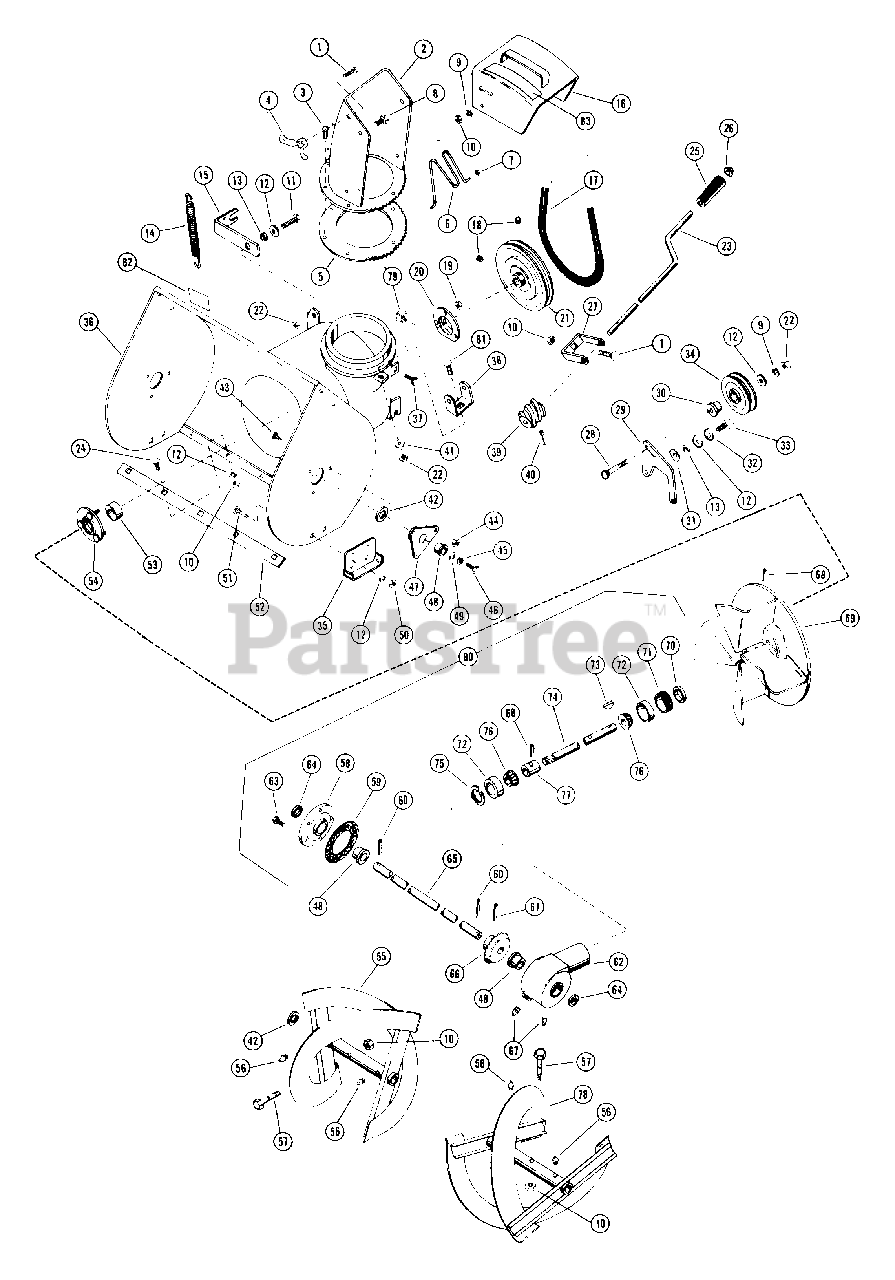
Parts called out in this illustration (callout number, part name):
1	BLT-RDHDSQSHNK .31-18X.50 YZ
2	DISCHARGE CHUTE
3	SCR-TAP 8-32X.38 SL HWH PL 23
4	WING NUT, .312-18
5	LOWER COLLAR GEAR
6	SAFETY WIRE
7	FASTENER
8	BLT-HEX .31-18X.50 PL GR2
9	WSHR-LK .312X.097 PL HVY
10	NUT-LK .312-18 GR A PL
11	BLT-HEX .31-18X.75 PL GR2
12	WSHR-FL-STL .38X.875X.083 PL
13	SPACER BUSHING .5 X .32 X .21
14	SG-TENS .125X.437X5.5 WLD 20
15	CLUTCH LEVER
16	DEFLECTOR SERVICE ASSEMBLY
17	V-BELT, 4L-WRAPPED
18	SCR-SET .32-18X.38 SKHCUPNL OH
19	NUT-LK-CTR .250-20 PL
20	BEARING FLANGE
21	PLY-? 8.0X.75
22	NUT-HEX .312-18
23	CHUTE CONTROL CRANK
24	BLT-RDHDSQNK .312-18X.62 PL
26	CAP, 3/8 ROD YWZC
27	BRACKET
28	BLT-RDHDSQNK .31-18X1.38SHT PL
29	IDLER ARM
30	SPCR, BRG .315X.50X.688X.281
31	WAVE WASHER .531X.781X.125FH
32	WSHR-LK-INT .313X.030 PL
33	BLT-HEX .31-18X.63 PL GR 2
34	IDLER
35	RUNNER
36	BLOWER HOUSING
36	BLOWER HOUSING 24 IN
37	BLT-SCRHFWH .38-16X.75 PL
38	WORM CLEVIS
39	WORM GEAR
40	PIN-ROLL .125X.75
41	WSHR-LK .313X.062
42	WSHR-FL-STL 1.010X1.505X.062PL
43	SCR-SLTR-SERNK .25-20X.62 PL
44	NUT-LK-FLG .250-20 PL
45	WSHR-LK .500X.151 HVY PL
46	BLT-HEX .50-13X1.00 PL GR2
47	BEARING SUPPORT
48	BSHG-FLG 1.000X1.12X.62X1.50BR
49	WSHR-FL-STL .511X1.441X.125 PL
50	NUT-LK-CTR .375-16 GR A PL
51	BLT-RDHDSQNK .38-16X.75 SHT PL
52	SCRAPER BLADE
53	BRG-BALL .750X1.750X.50
54	BEARING FLANGE
55	RAKE, RIGHT-20"(1ID X 13.88OD)
55	RAKE, RIGHT-24"(1ID X 13.75OD)
56	SPIN DRIVE ZERK FITTING
57	SHEAR BOLT YWZC
58	GEAR CASE FLANGE
60	PIN-ROLL .188X1.50
61	PIN-ROLL .313X1.38
62	CASE, GEAR - C.I.
63	BLT-SERHFWH .25-20X.75 PL
64	SEAL 1.000X1.312X.150
65	FRONT GEAR SHAFT
66	HELICON GEAR - 41 TOOTH
67	PIPE PLUG
68	PIN-ROLL .250X1.25
70	SEAL .750X1.499X.225
71	ADJUSTMENT PLUG
72	BRG-CUP 1.781X.475
73	KEY-WDRF .188X.75X.313 SAE 9
74	SHAFT
75	RG-RTNG INT 1.781 HSG X.062
76	BRG-CONE .750X.61
77	BEARING SPACER
78	RAKE, LEFT-20"(1ID X 13.88 OD)
78	RAKE, LEFT-24"(1ID X 13.75 OD)
79	NUT-RETNR .38-16 TINRMAN
80	GEAR CASE - C.I.
80	GEAR CASE - 24" - CAST IRON
81	BLT-RDHDSQNK .31-18X.75 GR5 PL
82	ARIENS NAME PLATE
83	PATENT LABEL
83	CAUTION LABEL
